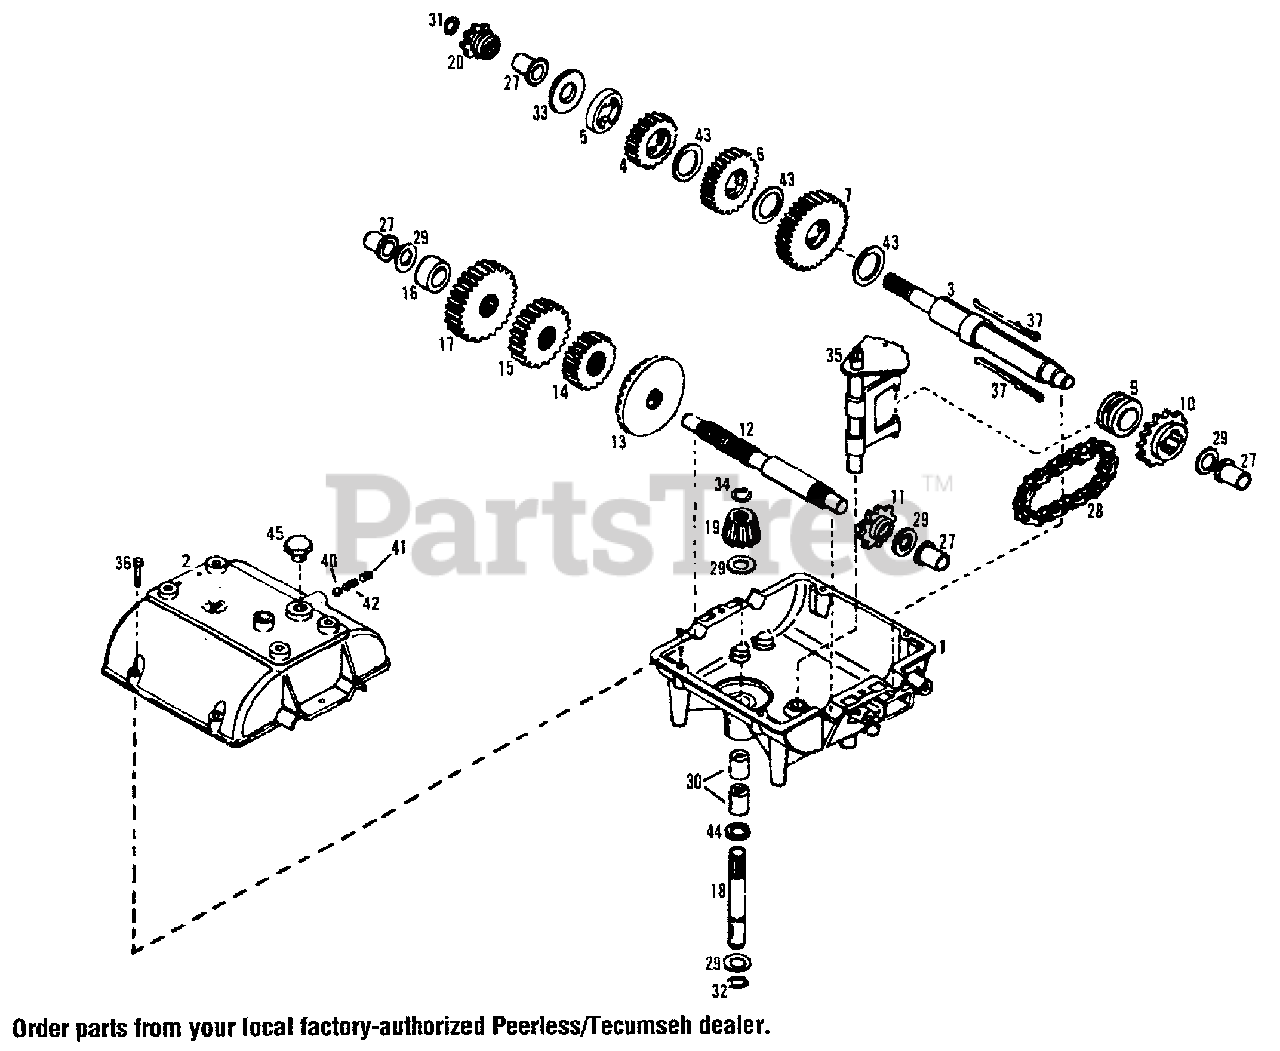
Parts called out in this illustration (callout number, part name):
1	Case, Transmission
2	Cover, Transmission
3	Shaft, Output
4	Gear, Spur (20 Teeth)
5	Spacer, Keyed
6	Gear, Spur (30 Teeth)
7	Gear, Spur (35 Teeth)
9	Collar, Shift
10	Sprocket (14 Teeth)
11	Sprocket (10 Teeth)
12	Shaft, Counter
13	Gear, Bevel (42 Teeth)
14	Gear. Spur (15 Teeth)
15	Gear, Spur (20 Teeth)
17	Gear, Spur (30 Teeth)
18	Shaft,lnput
19	Bevel Pinion, Input
20	Sprocket (8 Teeth)
27	Bushing, Flanged
28	Chain, Roller (No. 41 Chain, 22 Links)
29	Washer, Thrust
30	Bearing, Needle
31	Ring, Retaining
32	Ring, Retaining
34	Ring, Retaining
35	Rod & Fork Assembly, Shift
36	Screw, Flanged Hex Head Thread-Forming, 1/4-20 x 1-1/4
40	Ball, Steel, 5/16"
41	Screw, Set, 3/8-16 x 3/8
42	Spring
43	Washer, Thrust
44	"O" Ring
